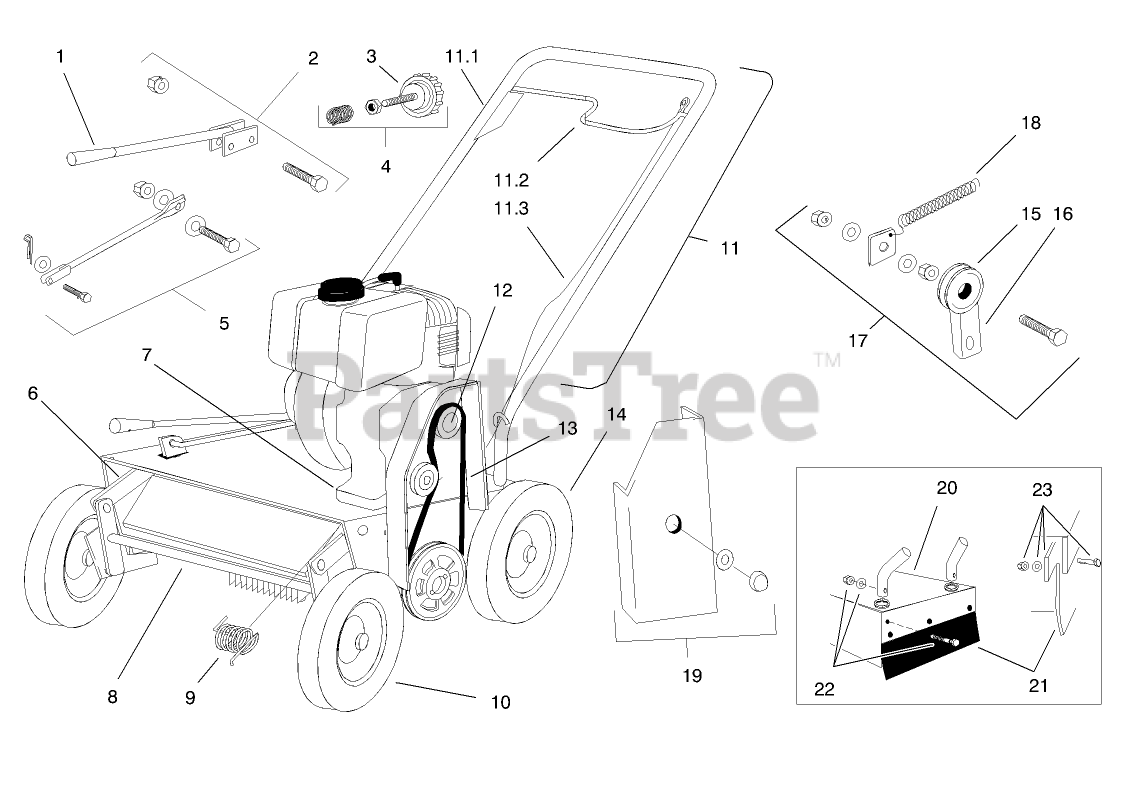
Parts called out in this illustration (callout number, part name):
1	KNOB
2	KIT - LEVER
3	KNOB
4	KIT - HEIGHT ADJUSTMENT
5	KIT - PUSH ROD
6	ARM - TORQUE
7	PLATE
8	AXLE
9	SPRING
10	WHEEL
11	HANDLE
11.1	HANDLE
11.2	HANDLE - CLUTCH
11.3	CABLE - CLUTCH
12	V-PULLEY
13	V-BELT
14	WHEEL
15	ARM - MOUNTING
16	PULLEY
17	KIT - PULLEY
18	SPRING - CLUTCH
19	ASSEMBLY - SHIELD
20	WA - HOUSING
21	DEFLECTOR
22	KIT - BOLT
23	KIT - STRAP
